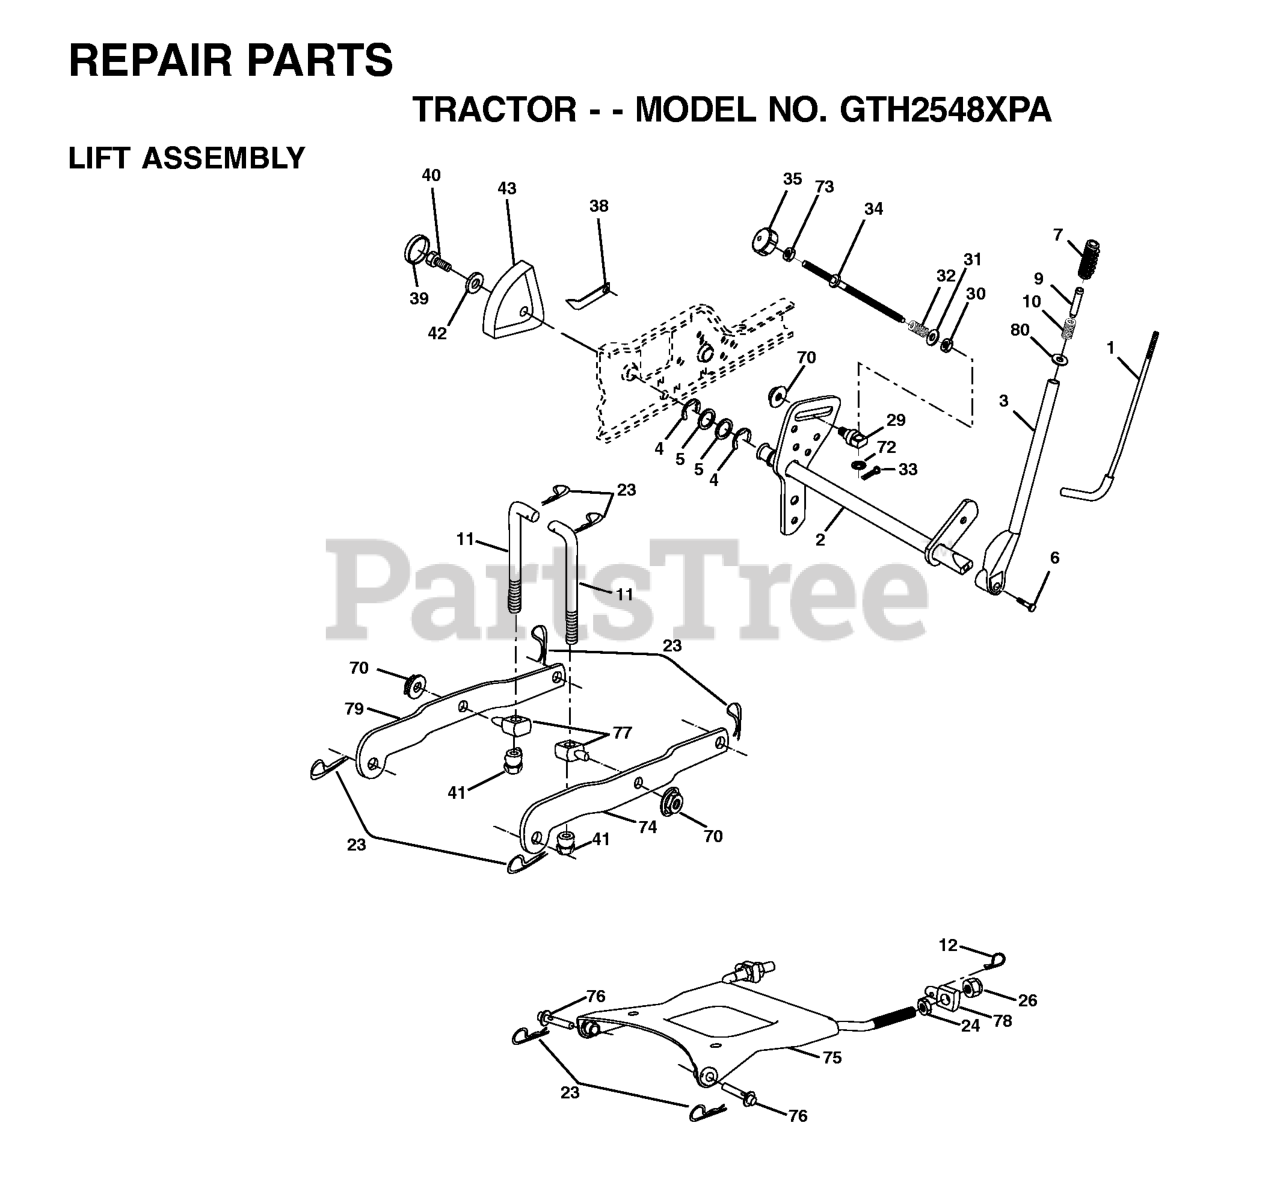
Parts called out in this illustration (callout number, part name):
1	LEVER ROD LT
2	SHAFT ASM., LIFT VGT
3	LEVER ASSY-LIFT RH
5	Washer 29/32 x 1 - 1/4 x 16 Ga.
6	Bolt, Fin Hex 3/8-16 x 1-1/12
7	GRIP HANDLE
8	PLUNGER BUT KIT
9	PLUNGER BUT KIT
10	SPRING**
11	LIFT LINK
12	SPRING RETAINER
14	BEARING.PIVOT.LIFT
23	RETAINER-SPRNG RB
24	NUT.HEX.JAM.1/2-13
26	NUT.LK.W/WSH.1/2.
32	SPRING.COMP.INF.H
33	COTTER PIN
34	ROD.LIFT.ADJUSTABLE
35	KNOB INF 3/8-16
38	POINTER, HEIGHT INDICATOR(2 2)
40	SCREW 5/16-18X1
41	NUT, LIFT LINK 7/16-20
43	HEIGHT INDICATOR
70	NUT
72	NUT PUSH M
73	NUT
74	ARM SUSP REAR RH
75	PLATE ASM SUSP FRONT
76	PIN.FLANGE
79	ARM SUSP. REAR LH
80	WASHER
